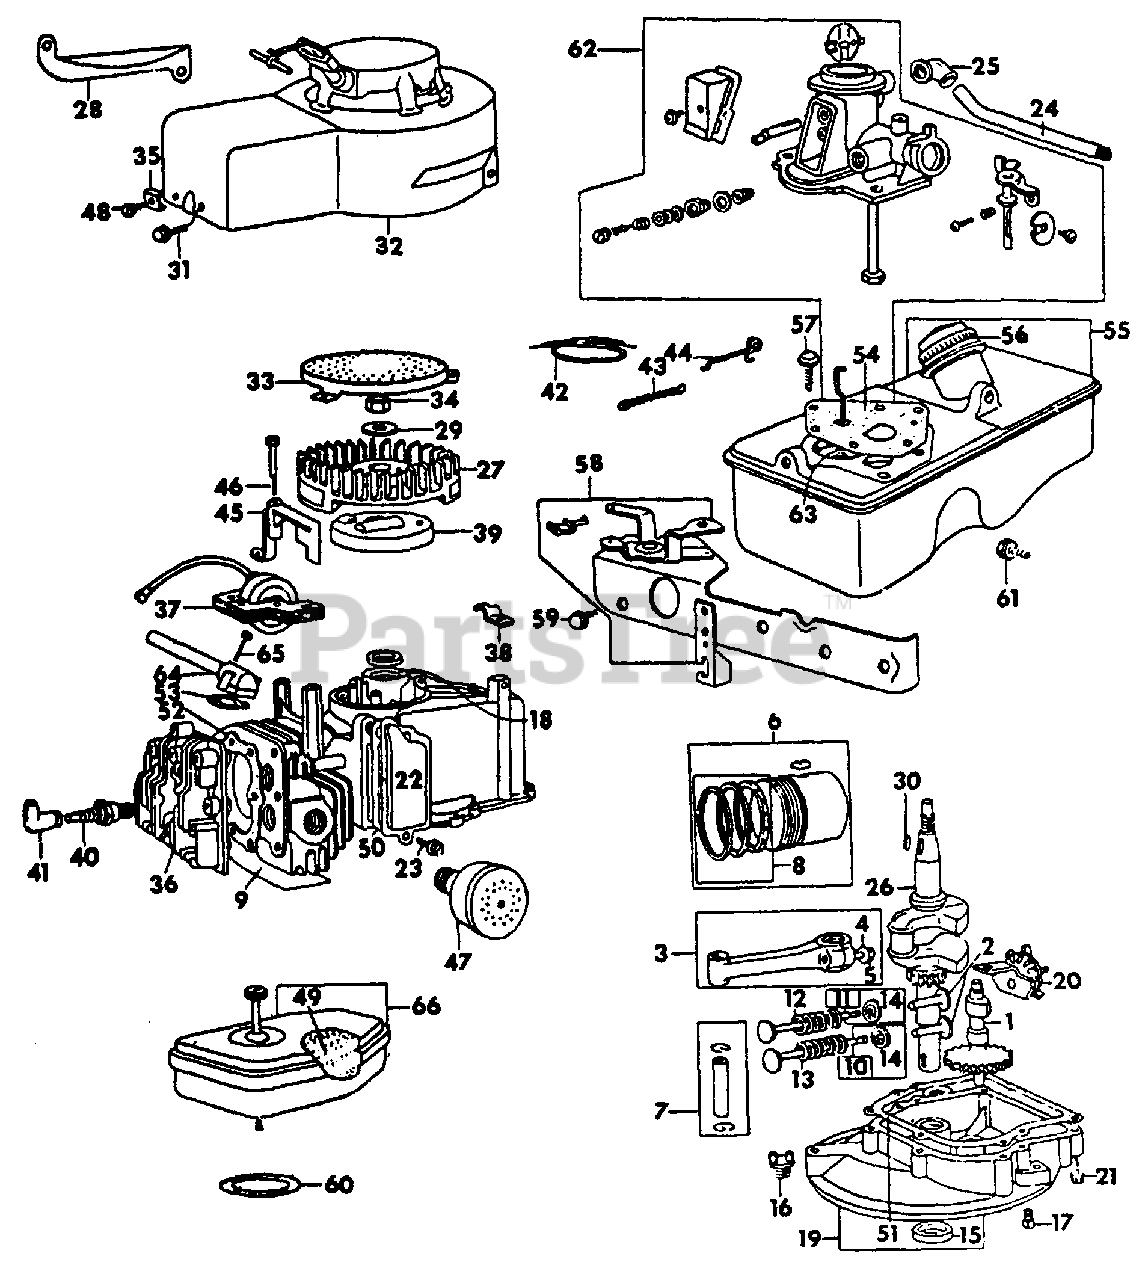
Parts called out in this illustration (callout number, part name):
2	TAPPET, VALVE
3	ROD ASSY, CONNECTING - STD
4	LOCK, SCREW HEAD
5	SCREW, CONNECTING ROD
5	RING SET, PISTON CHROME - STD
6	PISTON ASSY. - STD
7	PIN, PISTON AND RETAINER - STD
8	RING SET, PISTON - STD
9	SHIELD, CYLINDER
10	VALVE, INTAKE
11	VALVE, EXHAUST
12	SPRING, INTAKE VALVE
13	SPRING, EXHAUST VALVE
14	RETAINER, VALVE SPRING
16	PLUG, OIL FILLER
17	PLUG, 3/8-18 AUTOMOTIVE SQ-HD
18	SEAL, OIL
20	BRACKET, OIL SLINGER GEAR
21	SCREW, SUMP MOUNTING
22	BREATHER, VALVE CHAMBER
23	SCREW, BREATHER MOUNTING
24	TUBE, BREATHER
25	GROMMET, BREATHER TUBE
28	GUARD, FLYWHEEL
29	WASHER, FLYWHEEL
30	KEY, FLYWHEEL
31	SCREW, BLOWER HOUSING MOUNTING
32	HOUSING, BLOWER
33	SCREEN, ROTATING
34	NUT, FLYWHEEL
35	CLAMP, CASING
36	HEAD, CYLINDER
37	ARMATURE, MAGNETO
38	CLAMP, CONDENSOR
39	COVER, BREAKER POINTS
40	PLUG, SPARK -CHAMPION-
41	ELBOW, SPARK PLUG INSULATOR
42	WIRE, GROUND
43	SPRING, GOVERNOR
44	SPRING, GOVERNOR LINK
45	BLADE, GOVERNOR
47	MUFFLER, EXHAUST
48	SCREW W/LOCKWASHER HEX-HD
49	ELEMENT, AIR CLEANER
50	GASKET, VALVE COVER
52	GASKET, CYLINDER HEAD
53	GASKET, INTAKE ELBOW
54	DIAPHRAM, CARBURETOR
55	TANK W/CAP, FUEL
57	SCREW, FUEL TANK MOUNTING
58	CONTROL, CARBURETOR PLATE
59	SCREW, CONTROL PLATE TO TANK
60	GASKET, AIR CLEANER MOUNTING
61	SCREW, FUEL TANK TO STARTER MOTOR
63	SPRING, DIAPHRAM
64	TUBE, FUEL INTAKE
65	SCREW, INTAKE ELBOW MOUNTING
66	CLEANER, AIR
